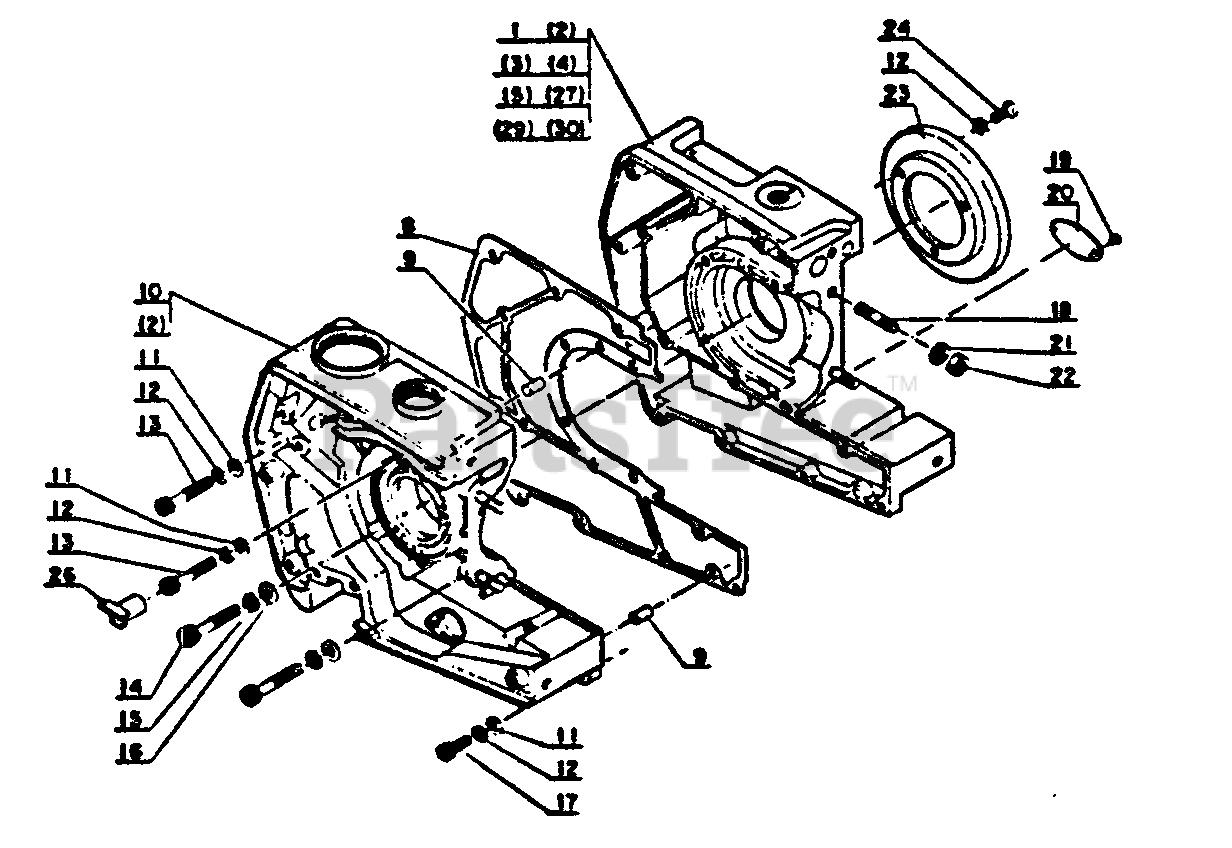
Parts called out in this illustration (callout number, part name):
1	CRANKCASE KIT
8	GASKET, CRANKCASE
9	PIN - LOCATING
10	CRANKCASE KIT
11	WASHER - 4
12	LOCKWASHER - 4
13	BOLT - 4X33
14	BOLT - 5X30
15	LOCKWASHER - 5
16	WASHER - 5
17	BOLT - 4X20
18	STUD
19	RIVET
20	PLATE, MODEL
21	WASHER - 5
23	SEAL, DUST
24	SCREW - 4X10
26	CLIP
